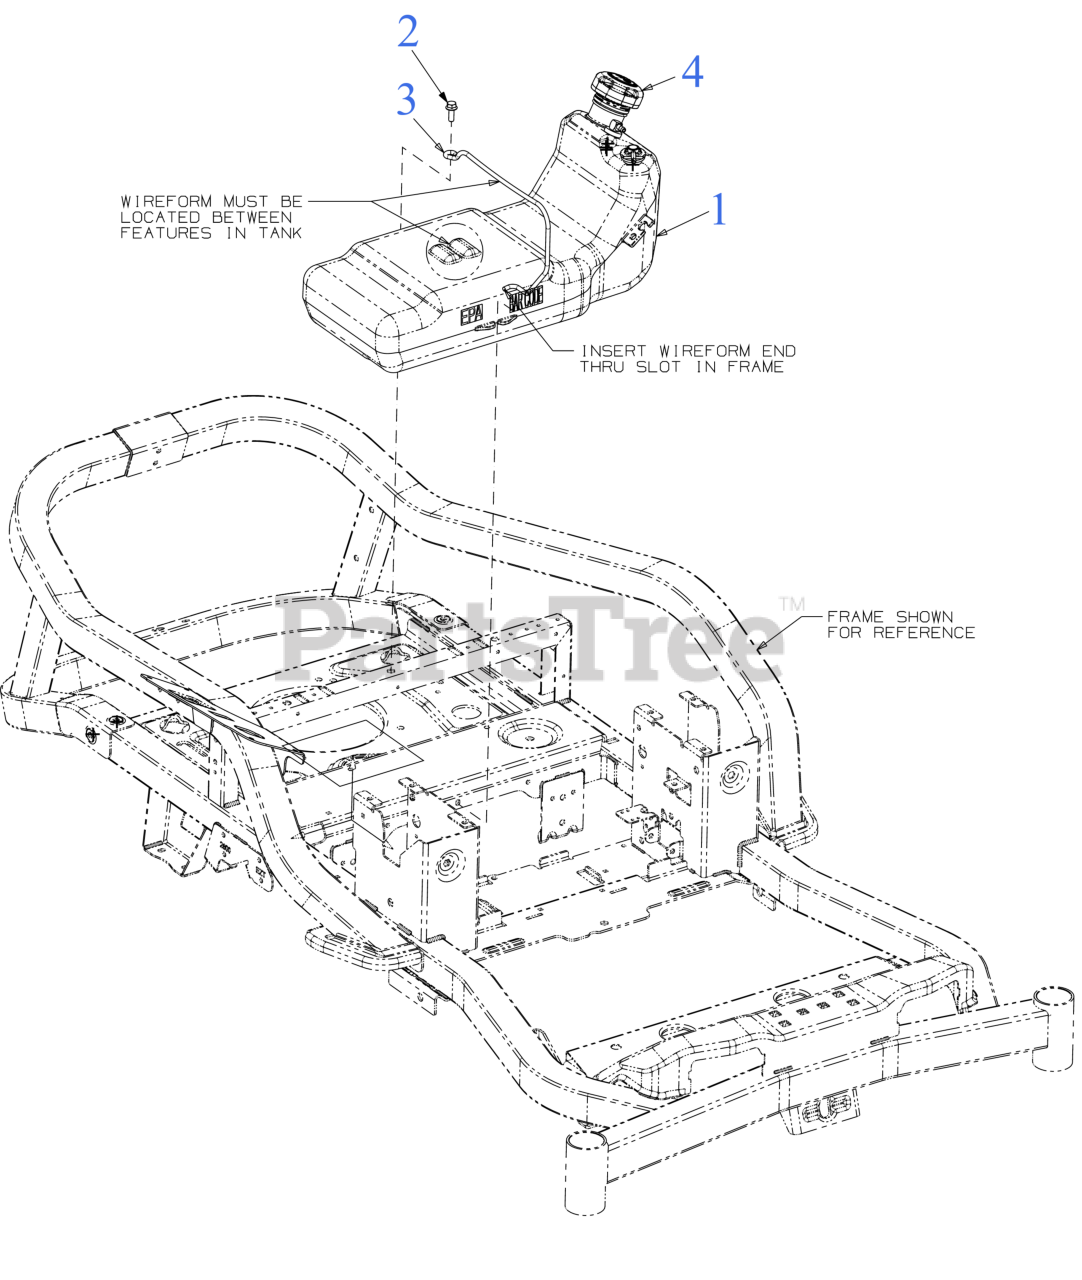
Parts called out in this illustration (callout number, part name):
1	FUEL TANK 3.5 GAL
2	SCREW 5/16-18 x .875 GR5 HXFLG HD
3	FUEL TANK RETAINER
4	FUEL CAP W/TETHER
